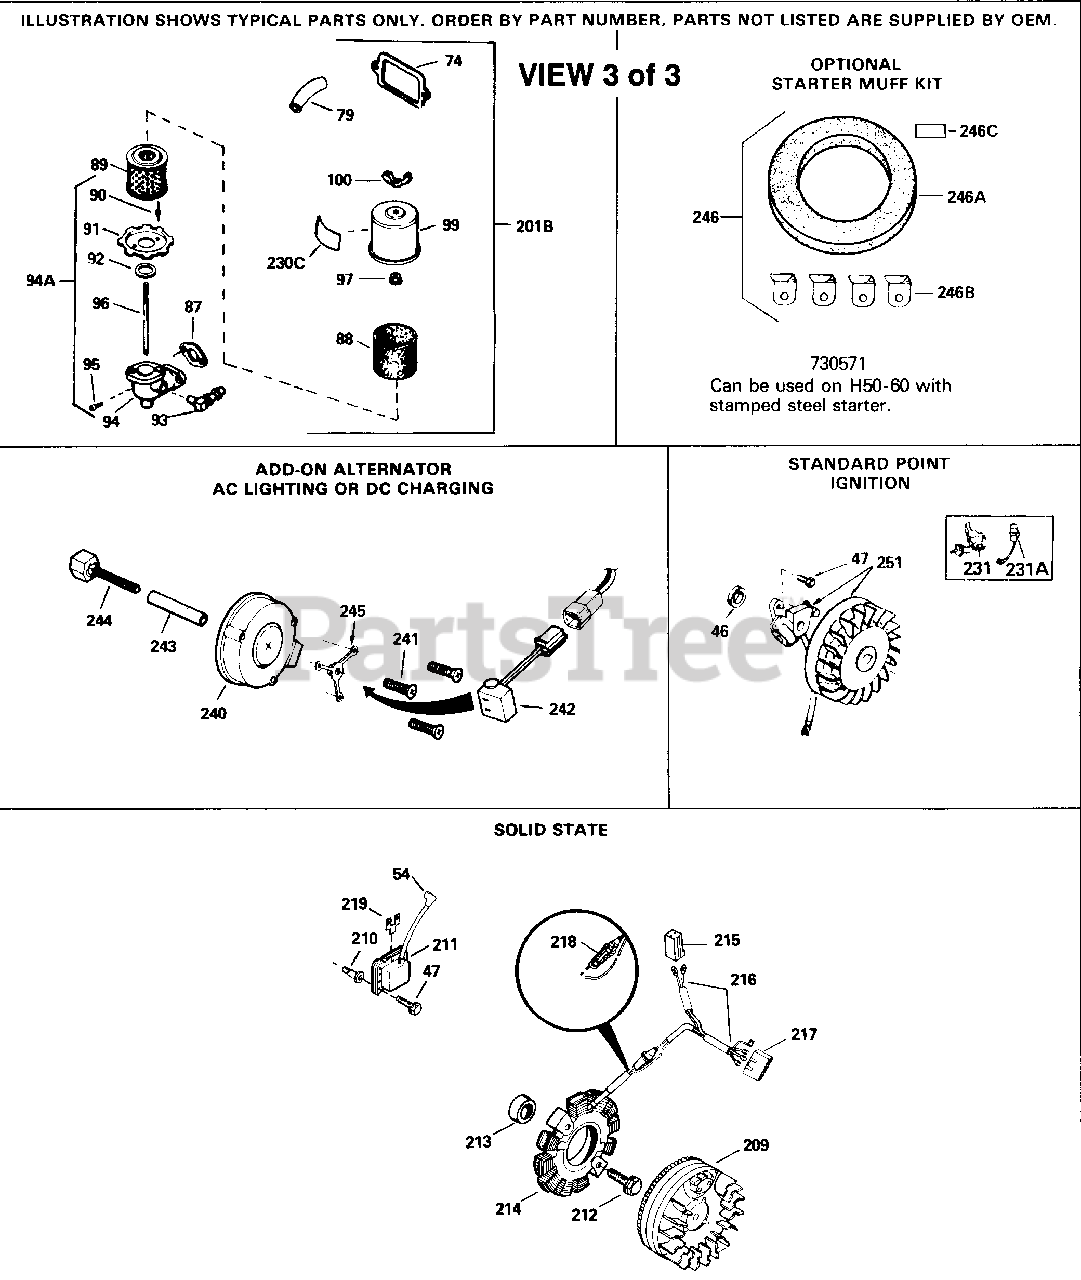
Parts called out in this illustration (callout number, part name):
15A	Governor Yoke
15B	Screw, 6-40 x 5/16"
46	Connecting Rod Bolt
74	Bearing Retainer
87	Screw, 1/4-20 x 1-3/4"
89	Flywheel Key
90	Flywheel
92	Belleville Washer
93	Flywheel Nut
100	Solid State Ignition
125	Exhaust Valve (Std.)(Incl. 151)
125	Exhaust Valve (1/32" OS) (Incl. 151)
126	Intake Valve (Std.) (Incl. 151)
126	Intake Valve (1/32" OS) (Incl. 151)
150	Valve Spring
173A	Breather Tube Grommet
184	* Carburetor To Intake Pipe Gasket
186	Governor Link
200	Control Bracket (Incl. 19, 203 & 204)
203	Compression Spring
209	Screw, 10-32 x 1/2"
210	Conduit Clip
211	Screw, 10-32 x 3/8"
224	* Intake Pipe Gasket
227	Air Cleaner Elbow (Machined)
228	Stud, 1/4-20 x 6.20"
229	Nut & Lock Washer, 1/4-20
235	Air Cleaner Elbow Fitting
238	Screw, 10-32 x 7/8"
239	* Air Cleaner Gasket
239A	* Air Cleaner Gasket
240	Air Cleaner Bracket
245	Air Filter
245A	Air Filter
251	Wing Nut, 1/4-20
260	Blower Housing
262	Screw, T-40, 5/16-24 x 21/32"
265	Cylinder Head Cover
272	Screw, 5/16-18 x 3/4"
273	Carburetor Flange
275	Muffler
285	Starter Cup
286	Starter Screen
287	Screw, 1/4-28 x 7/16"
291	Fuel Line
292	Fuel Line Clamp
298	Screw, 1/4-15 x 3/4"
299	"U" Type Nut
300	Fuel Tank (Incl. 292 & 301)
301	Fuel Cap (Red)
305	"O" Ring
305	Oil Fill Tube
308	Fill Tube Clip
310	Oil Fill Plug
325	Wire Clip
340	Fuel Tank Bracket
341	Fuel Tank Bracket
342	Screw, 1/4-20 x 5/8"
366	Muffler Elbow
366A	Muffler Nipple
367	Lock Nut
370	Instruction Decal
370A	Logo Decal
370B	Instruction Decal
380	Carburetor (Incl. 184)
390	Rewind Starter
400	* Gasket Set (Incl. items marked PK in notes) Incl. part #'s 27272 (2), 2789 6 (2), 27913 (1), 27915 (2), 27930 (1 ), 28938B (1), 29673 (1), 30684 (1), 31688 (1), 33355 (1)
420	SAE 30 4-Cycle Engine Oil (Quart)
453	Engine Mounting Base
454	Screw, 5/16-18 x 3/4"
